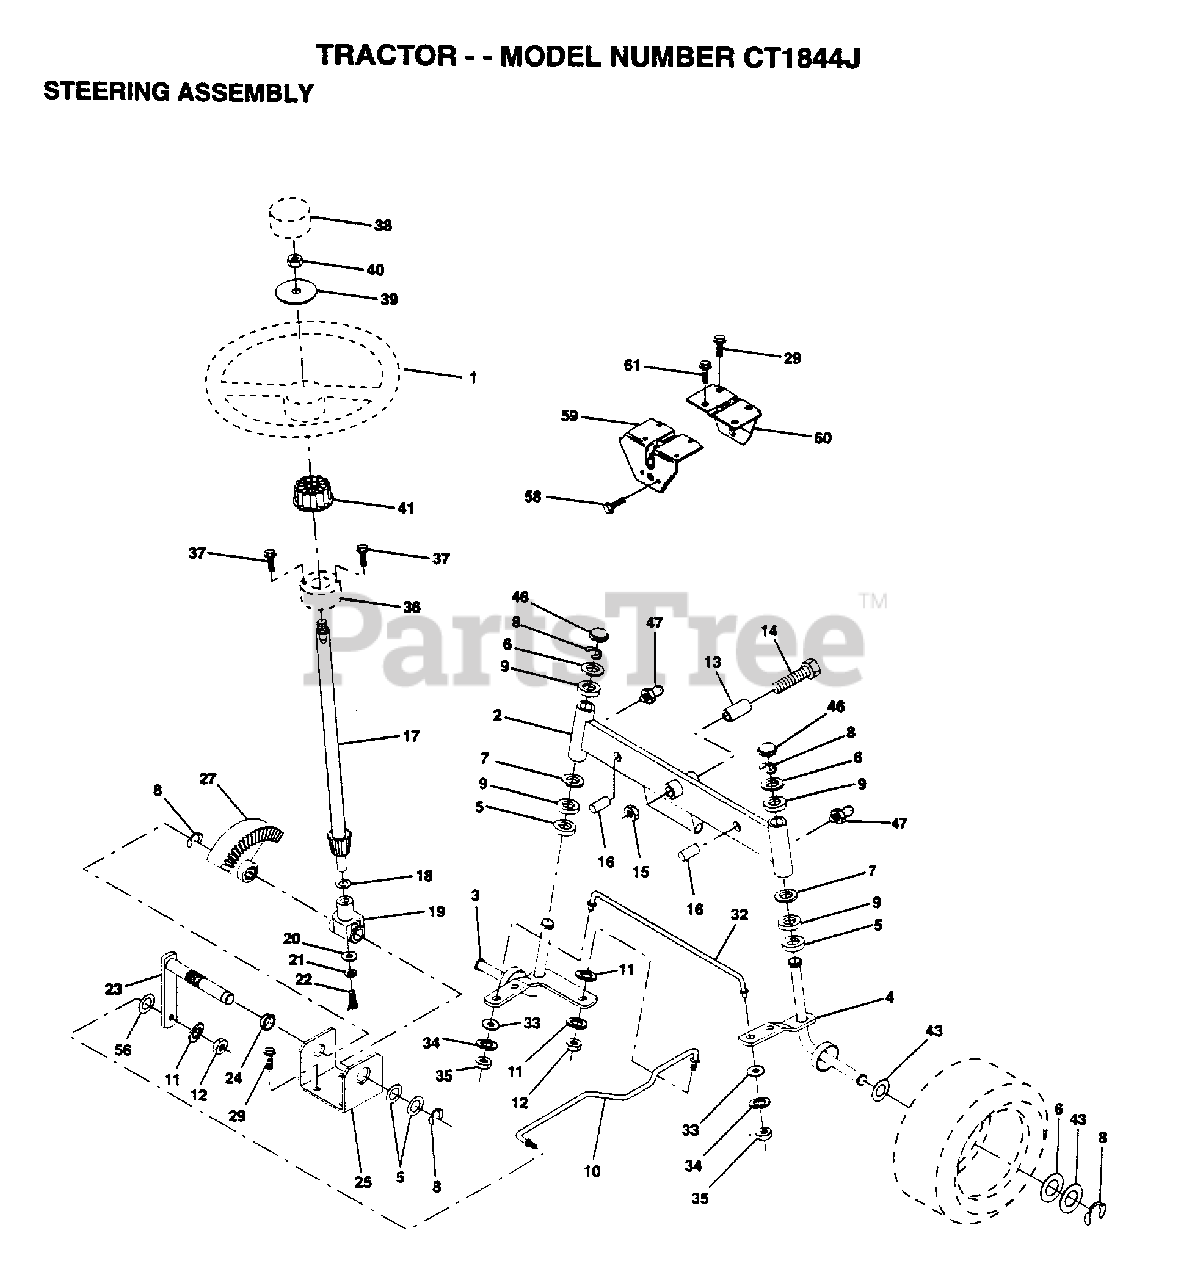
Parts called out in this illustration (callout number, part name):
1	WHEEL STR AYP BLK
2	AXLE ASM FRONT
5	WASHER .T
6	WASHER
7	WASHER
8	RING
9	COL. SRTG. BEAR.
11	LOCKWASHER
13	BEARING
14	BOLT LT
15	"NUT-LOC,FLANGE LT"
16	AXLE PIN
18	THRUST WASHER
19	SUPPORT.SHAFT
21	LOCKWASHER
22	"SCREW,SPECIAL"
24	NYLINER T
25	"BRKT,STEERING"
27	GEAR SECTOR
29	SCREW
32	TIE ROD
33	WASHER M
34	LOCKWASHER
35	NUT.LOCK.5/16-24
36	BUSHING.STRG.3/4
37	SCREW.10-24X1/2
38	CAP STEER AYP
39	WASHER
41	ADAPTER LT
43	WASHER
46	CAP
47	ZERK M
56	WASHER
58	SCREW LT
59	SUPPORT-SADDL T
60	SUPPORT.SADDLE.FT
61	SCREW SPECIAL
